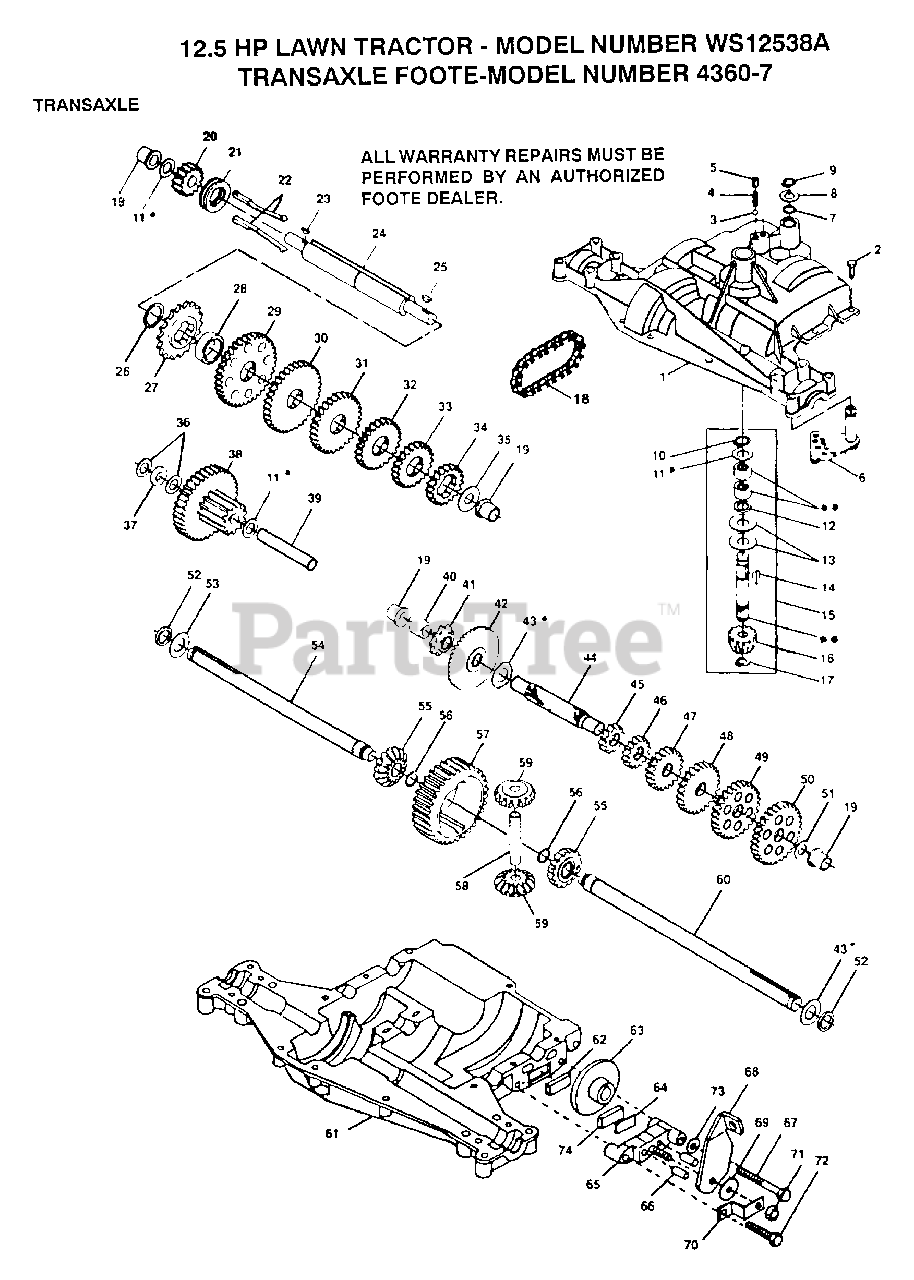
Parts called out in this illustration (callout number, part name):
1	HOUSING UPPER
3	BALL DETENT
4	SPRING, DETENT
5	SCREW, SET
6	ASSY SHIFTER
8	WASHER PLAIN
8A	WASHER PLAIN
8B	WASHER PLAIN
8C	WASHER PLAIN
8D	WASHER PLAIN
8E	WASHER PLAIN
8F	WASHER PLAIN
9	RING RETAINING
10	RING RETAINING
11	WASHER PLAIN
11A	WASHER PLAIN
11B	WASHER, PLAIN .632 X 1.00 X .026
11C	WASHER PLAIN
11D	WASHER PLAIN
11E	WASHER PLAIN
11F	WASHER PLAIN
11G	WASHER PLAIN
11H	WASHER, PLAIN .632 X 1.00 X .060
11I	WASHER PLAIN
13	WASHER, PLAIN .632 X 1.38 X .046
14	KEY WOODRUFF #9
15	ASSY KIT INPUT SHAFT
16	PINION, BEVEL, 14 TEETH
17	RING, RETAINING
18	CHAIN, 24 PITCHES
19	BEARING, FLANGE
20	GEAR SPUR, 14 TEETH
21	COLLAR CLUTCH
22	KEY CLUTCH
23	KEY WOODRUFF #3
24	SHAFT INTERMEDIATE
25	KEY, WOODRUFF, #61
26	RING, RETAINING
27	SPROCKET, 18 TEETH
29	GEAR, SPUR, 37 TEETH
30	GEAR, SPUR, 35 TEETH
31	GEAR, SPUR, 30 TEETH
32	GEAR, SPUR, 25 TEETH
33	GEAR, SPUR, 22 TEETH
35	WASHER, PLAIN .640 X 1.37 X .061
36	WASHER, PLAIN .632 X 1.00 X .026
37	SPACER .630 X 1.00 X .169
38	ASSY GEAR COMB 12&35 TEETH
39	SHAFT IDLER
40	SPACER .635 X .875 X .755
41	SPROCKET, 9 TEETH
42	GEAR, BEVEL, 42 TEETH
43	WASHER PLAIN
43A	WASHER PLAIN
43B	WASHER PLAIN
43C	WASHER PLAIN
43D	WASHER PLAIN
43E	WASHER PLAIN
43F	WASHER, PLAIN .758 X 1.25 X .031
43G	WASHER PLAIN
43H	WASHER PLAIN
43I	WASHER PLAIN
43J	WASHER PLAIN
43K	WASHER PLAIN
43L	WASHER PLAIN
44	SHAFT, DRIVE
45	GEAR, SPUR, 12 TEETH
46	GEAR SPUR, 15 TEETH
47	GEAR, SPUR, 20 TEETH
48	GEAR, SPUR, 25 TEETH
49	GEAR, SPUR, 28 TEETH
50	GEAR, SPUR, 31 TEETH
51	WASHER, PLAIN .632 X 1.00 X .060
53	WASHER PLAIN
54	AXLE LEFT HAND
55	GEAR, MITER, 15 TEETH
56	RING, RETAINING
57	GEAR, SPUR, 32 TEETH
58	SHAFT, CROSS
59	GEAR, MITER, 15 TEETH
60	AXLE, R.H.
61	HOUSING LOWER
62	PUCK, FRICTION
63	DISC, BRAKE
65	JAW, BRAKE
66	PIN, DOWEL
67	SCREW TAPPING
68	LEVER, ACTUATING
69	WASHER, PLAIN .321 X 1.00 X .055
70	BRACKET, ANTI-ROTATION
71	LOCKNUT 5/16-24
72	SCREW TAPPING
73	WASHER PLAIN
74	PUCK, FRICTION
